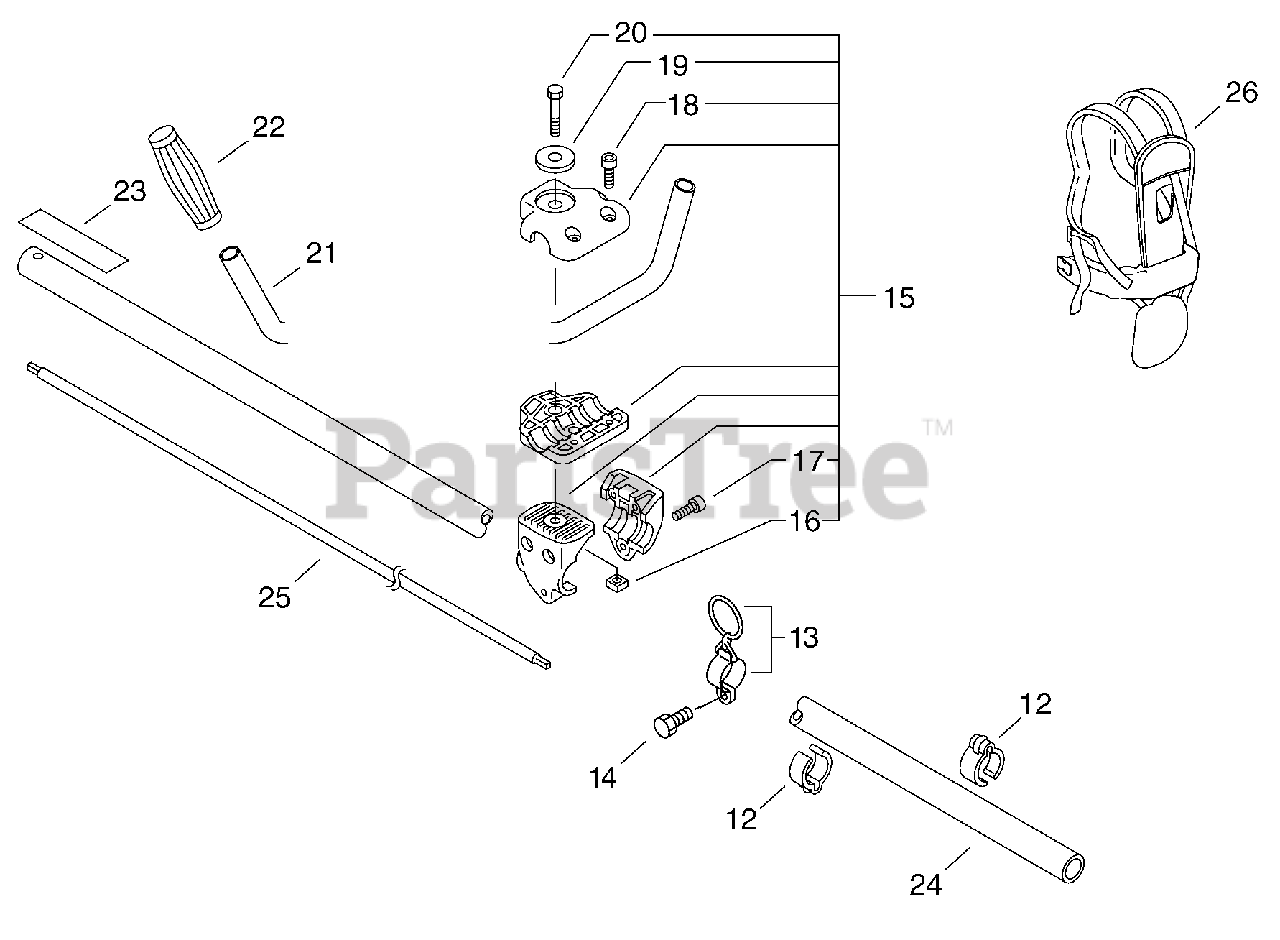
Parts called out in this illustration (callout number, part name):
13	HANGER KIT
14	SCREW - 5X12
15	HANDLE BRACKET KIT
17	SCREW - 5X30
18	SCREW - 5X20
19	WASHER - 8
20	BOLT - 8X55
21	HANDLE - FRONT
22	GRIP, HANDLE - LEFT
23	LABEL - CAUTION
24	PIPE, MAIN
25	DRIVESHAFT
26	HARNESS ASSY
